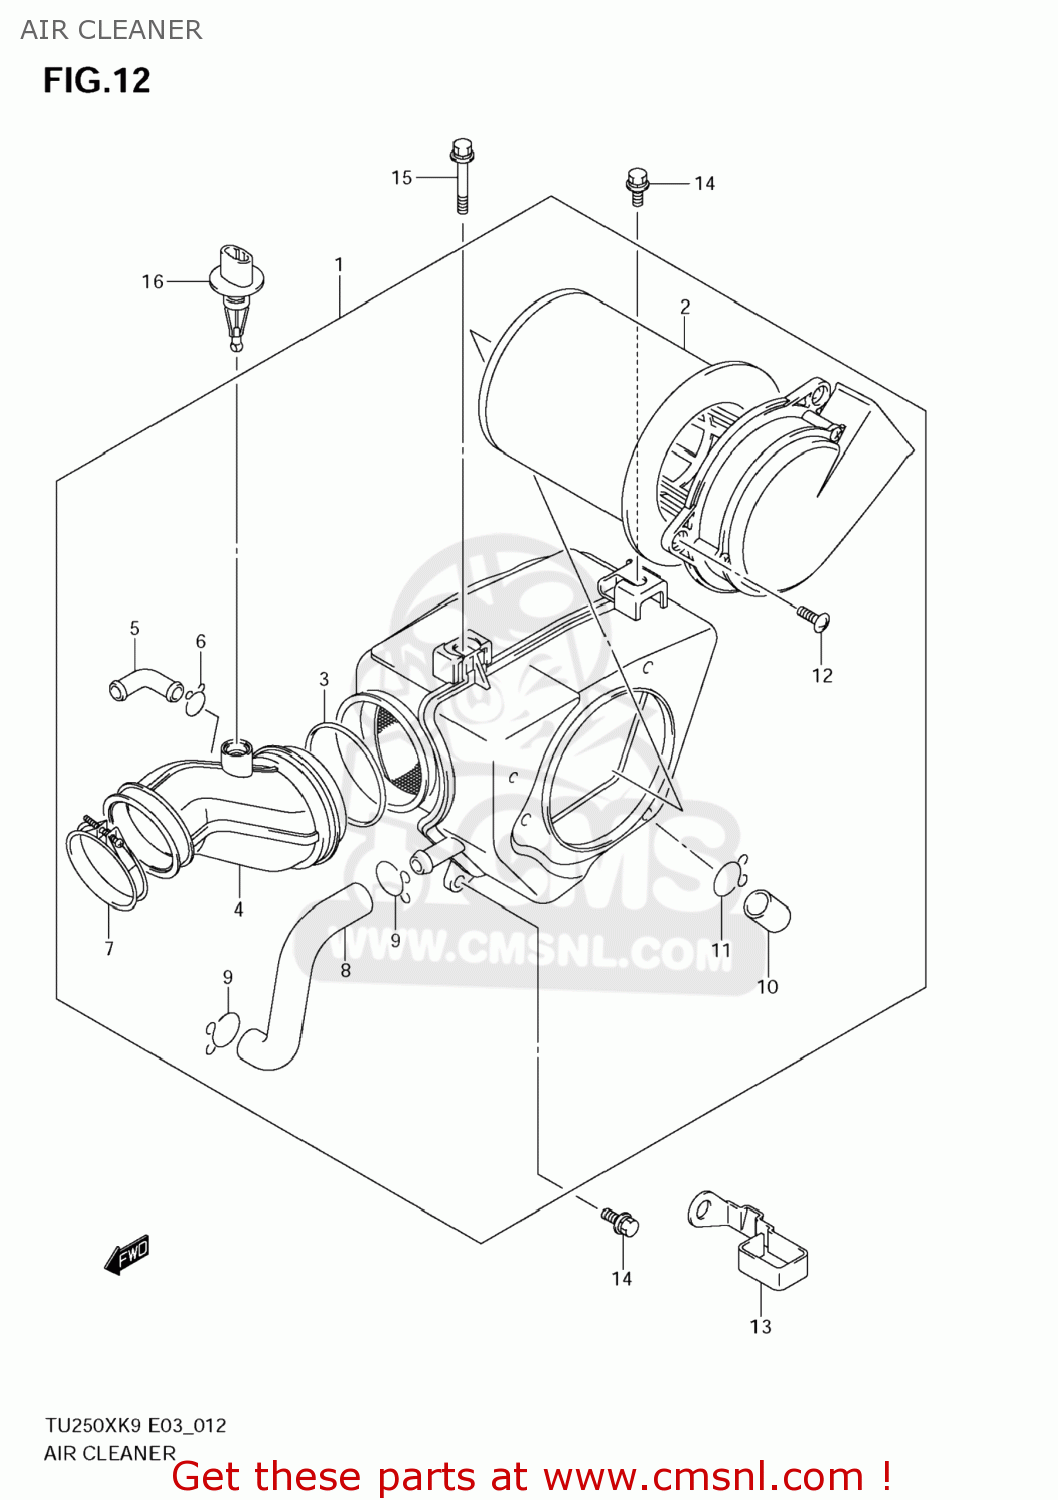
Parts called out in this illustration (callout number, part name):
1	CLEANER ASSY,AI
2	FILTER
3	CLAMP,AIR CLEANER SIDE
4	TUBE,OUTLET
5	JOINT
6	CLIP
7	CLAMP
8	TUBE,BREATHER
9	CLIP
10	PLUG
11	CLIP
12	SCREW
13	CLAMP,AIR CLEANER DRAIN TUBE
14	BOLT
15	BOLT
16	SENSOR,INLET AIR TEMP
